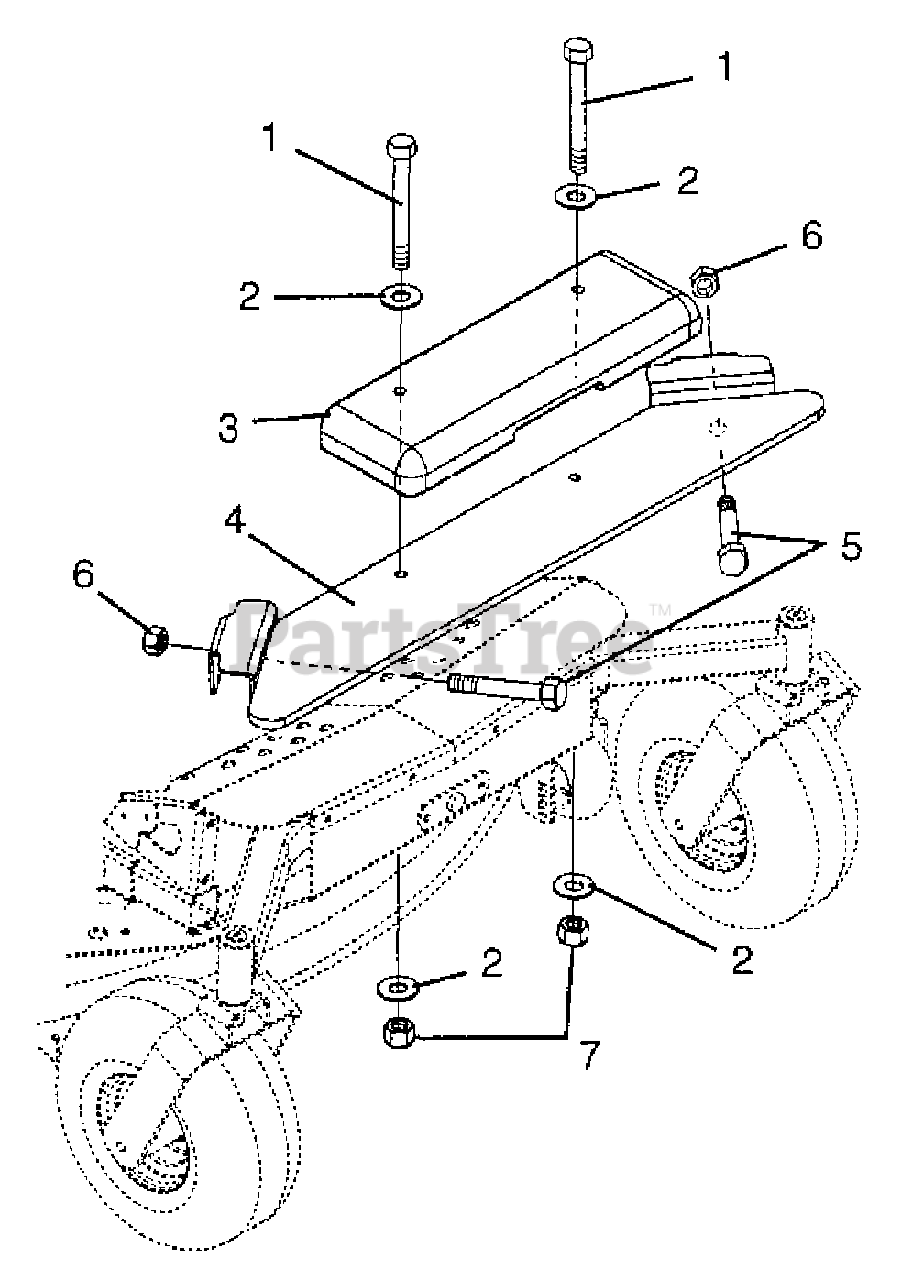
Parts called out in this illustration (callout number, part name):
1	Bolt-Hex .50-13 x 3.50
1	Bolt-Hex .50-13 x 5.50
2	Washer Flat Steel .51 x 1.00x.062
3	Counterweight
4	Bracket-Counterweight
5	Bolt-Hex .38-16 x 3.00
6	Nut-Locking-Nylon .38-16
7	Nut-Locking-Nylon .50-13
